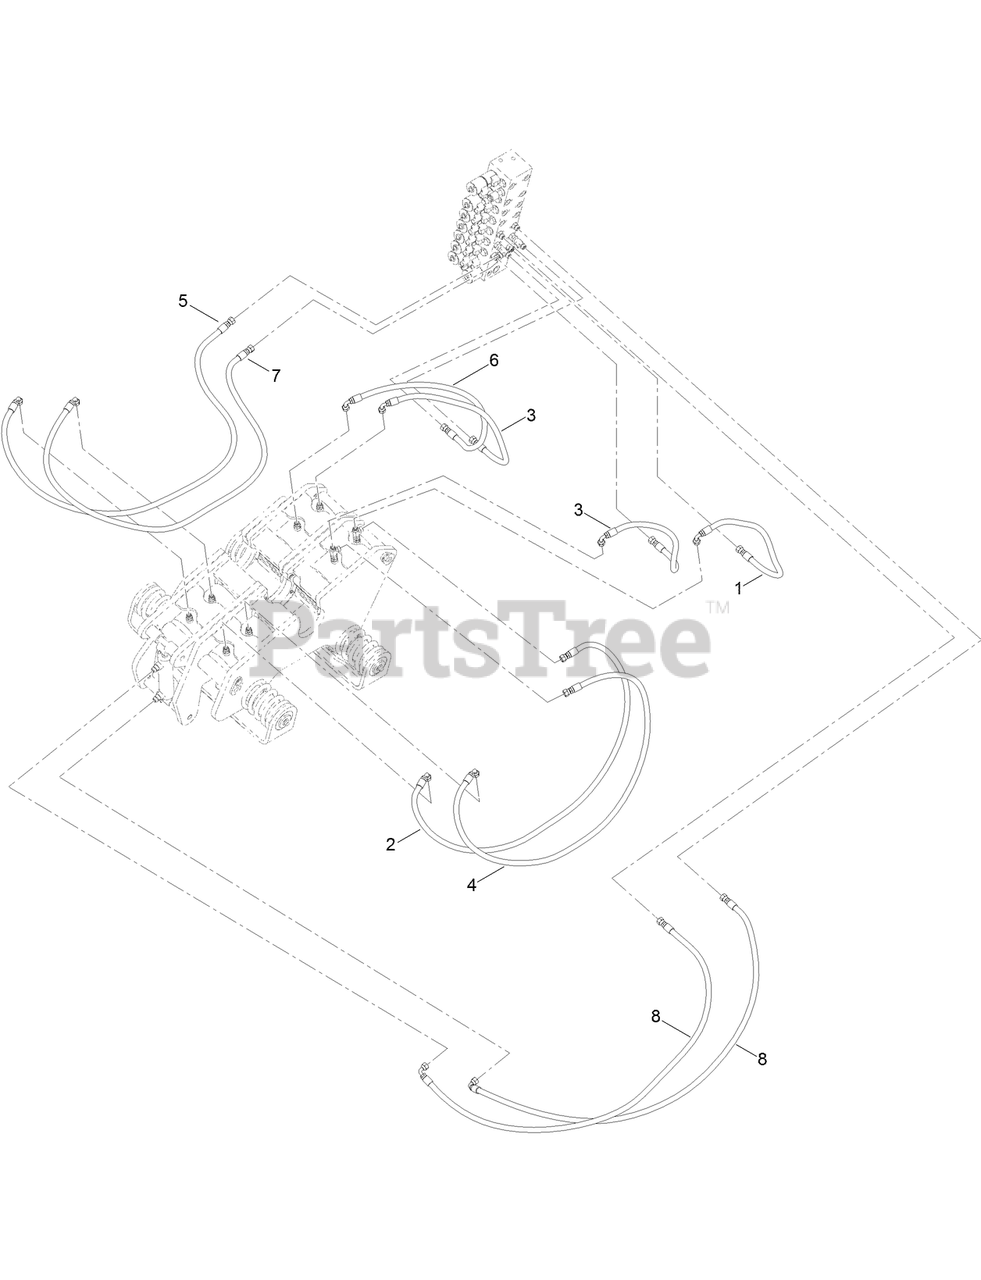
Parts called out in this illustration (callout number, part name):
1	HOSE ASM-HYD
2	HOSE ASM-HYD
3	HOSE ASM-HYD
4	HOSE ASM-HYD
5	HOSE ASM-HYD
6	HOSE ASM-HYD
7	HOSE ASM-HYD
8	HOSE ASM-HYD
